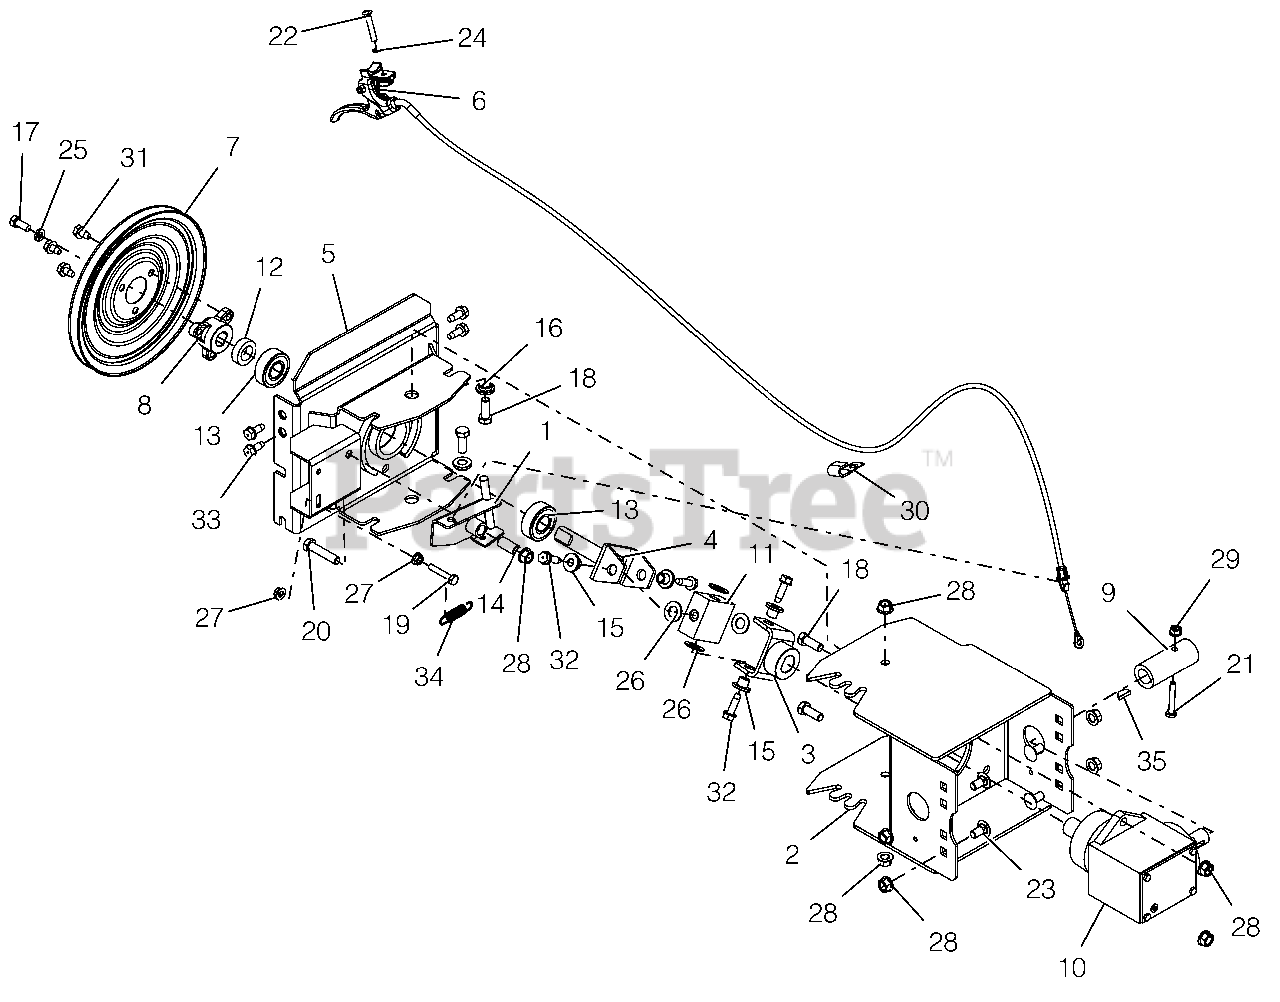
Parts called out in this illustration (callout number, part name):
1	ARM, PIVOT LOCK
2	ADAPTER WITH DECAL,BRUSH FRAME
3	JOINT,UNIVERSAL
4	JOINT,UNIVERSAL
5	ADAPTER, FRAME-20000 SERIES
6	CABLE, REMOTE BRUSH LOCK
7	PULLEY,SPIN FORM SINGLE GROOVE
8	PULLEY HUB, BOLT-ON D-BORE .75
9	HUB, COUPLING
10	GEAR BOX ASSEMBLY
11	BLOCK, UNIVERSAL
12	SPACER .755X1.250X.370
13	BRG-BALL .750X1.781X.61
14	BSHG-SLV .385X.500X1.045
15	BSHG-FLG .325X.500X.513X.875
16	BSHG-FLG .406X.88X.270X.140
17	BLT-HEX .31-24X.75 YWZC GR5
18	@BLT-HEX .38-16X1.00 GR5 YWZC
19	@BLT-HEX .25-20X1.50 GR5 YWZC
20	@BLT-HEX .38-16X1.75 GR5 YWZC
21	@BLT-HEX .25-20X1.75 GR5 YWZC
22	SCR-MCH .25-20X1.50 OVAL HD
23	@BLT-RDHDSQNK .38-16X.75 G5YZ
24	WSHR-LK-INT .250 TH TYA
25	WSHR-LK .312X.097 HVY YWZC
26	WSHR-HDND-STL-THR.515X.97X.062
27	@NUT-SPNLK-FLG .25-20 YWZC
28	@NUT-LK-TOP-FLG .38-16 YWZC
29	@NUT-LK-TOP-FLG .25-20 YWZC
31	@SCR-TAP .31-18X.50 HWH TR YWZ
32	@SCR-TAP .31-18X1.00 HWH TR YZ
33	@SCR-TAP .31-18X.75 HWH TR YWZ
34	SG-TENS .06X.46X2.00
35	KEY-WDRF .188X.75X.313 SAE 9
